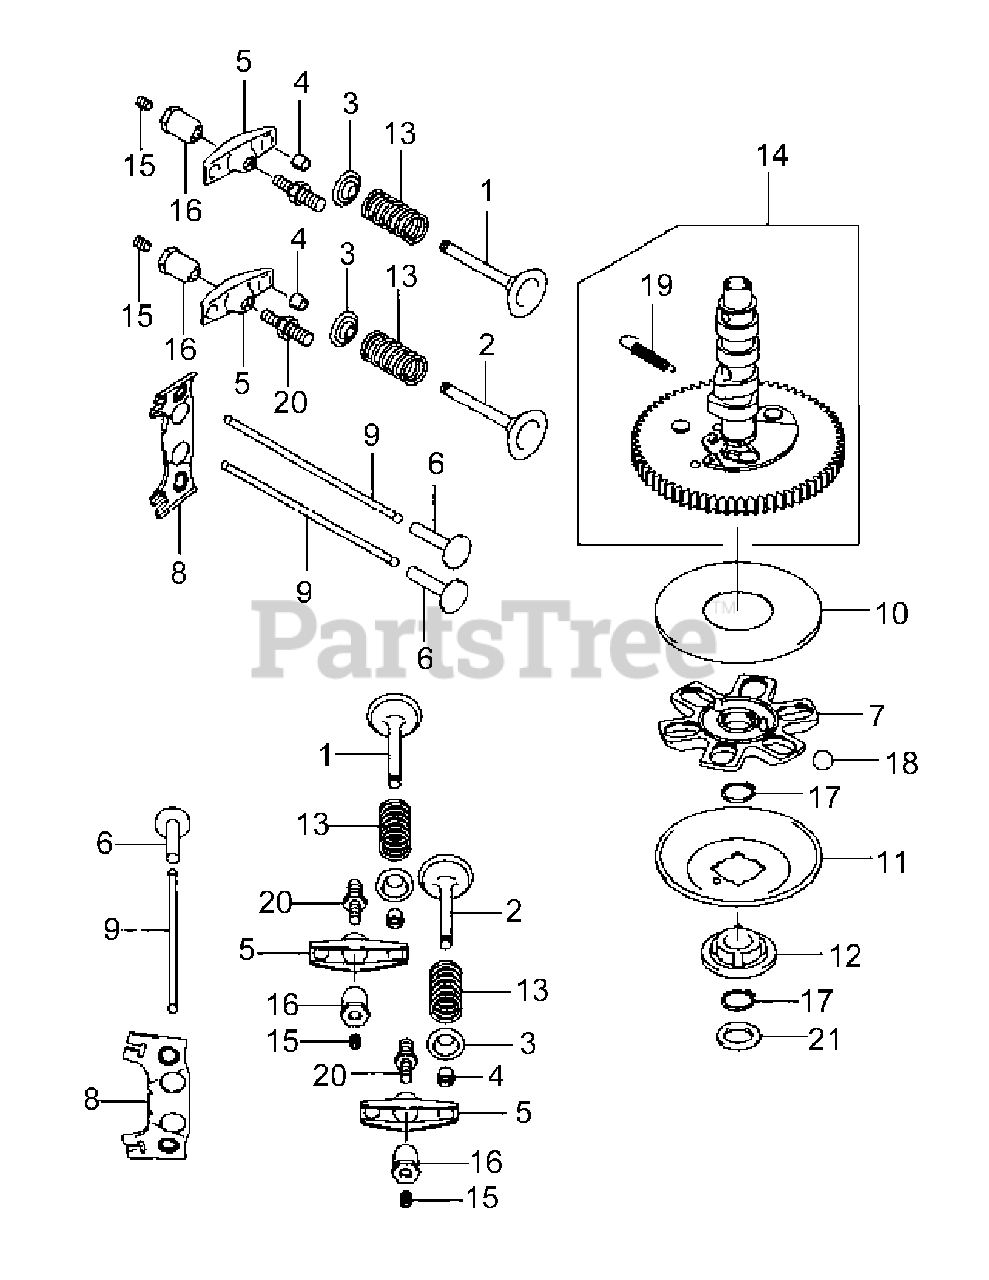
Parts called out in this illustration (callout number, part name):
2	VALVE-EXHAUST
3	RETAINER-VALVE SPRING
11	PLATE, GOVERNOR
13	SPRING-ENGINE VALVE
14	CAMSHAFT-COMP
17	RING-SNAP
18	BALL
19	SPRING
